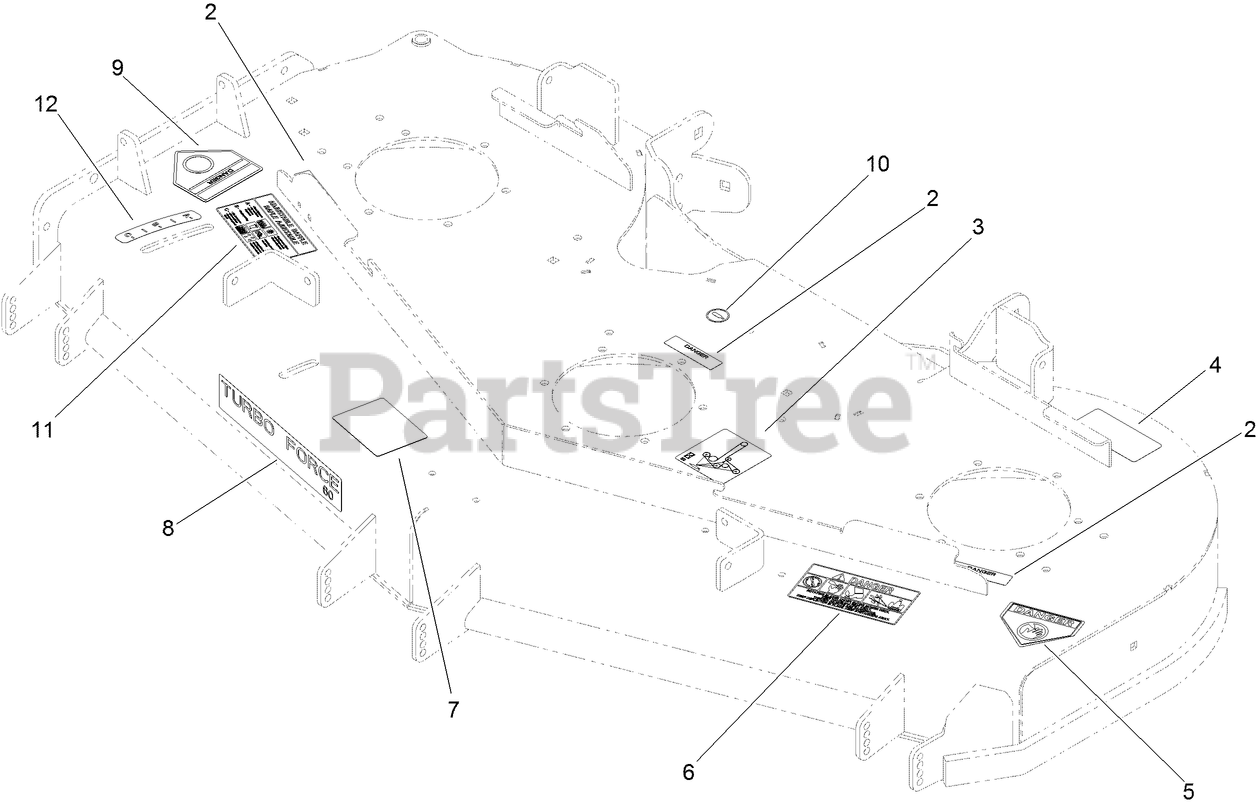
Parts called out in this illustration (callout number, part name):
2	DECAL-COVER, MISSING
3	DECAL-ROUTING, DECK BELT
4	DECAL-TORQUE
5	DECAL-DANGER
6	DECAL-DANGER, THROWN OBJECT
7	DECAL-SCALP, ANTI
9	DECAL-DANGER
10	DECAL-GREASE
11	DECAL-ADJUSTMENT, BAFFLE
12	DECAL-SETTING, BAFFLE
